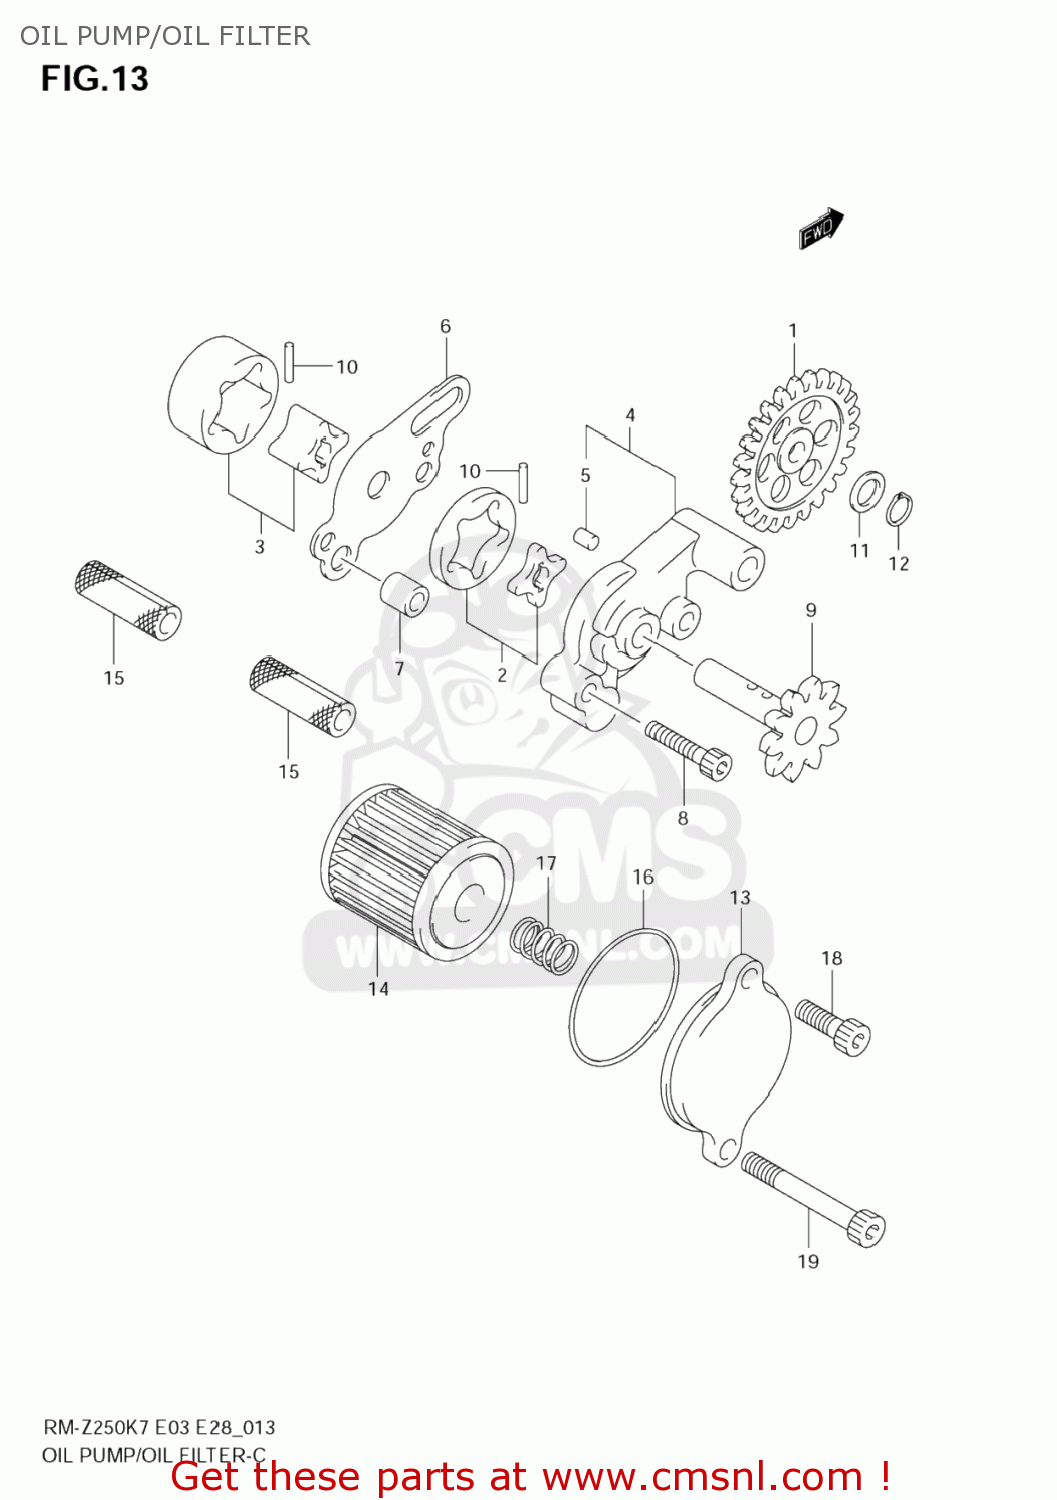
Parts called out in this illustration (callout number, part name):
1	GEAR,OIL PUMP IDLE
2	ROTOR SET,OIL PUMP NO.1
3	ROTOR SET,OIL PUMP NO.2
4	COVER,OIL PUMP
5	PIN
6	PLATE,OIL PUMP
7	PIN
8	BOLT
9	SHAFT,OIL PUMP DRIVEN GEAR
10	PIN(2.5X11.8)
11	SHIM(8X18X0.5)
12	CIRCLIP
13	CAP,ENG OIL FILTER OUTER
14	FILTER ASSY,ENGINE OIL
15	STRAINER,ENGINE OIL
16	O RING(D:2,ID:38.5)
17	SPRING
18	BOLT(6X16)
19	BOLT(6X35)
